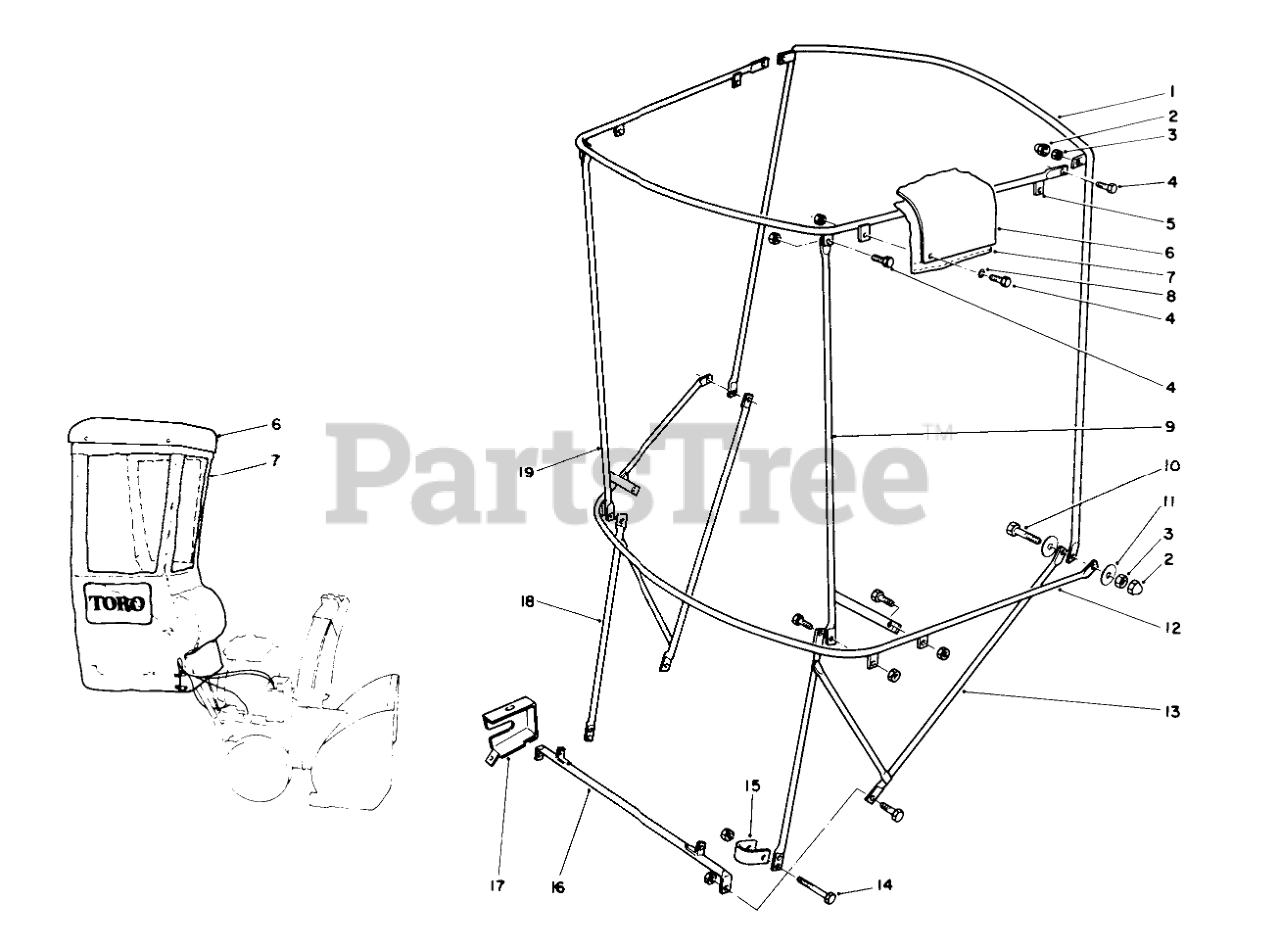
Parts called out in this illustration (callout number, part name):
1	VERTICAL BOW
2	CAPLUG
3	NUT-HEX, SIDE DEFORM
4	SCREW-HH
5	FRAME - TOP
6	Top-Plastic
7	Cover-Vinyl
8	WASHER-FLAT
9	CORNER POST - LH
10	SCREW-HH
11	WASHER-FLAT
12	HORIZONTAL BOW
13	Bracket-LH
14	SCREW-HH
15	CLAMP
16	Bracket-Base
17	COVER-LOCK, LEVER
18	BRACKET-RH
19	CORNER POST - RH
